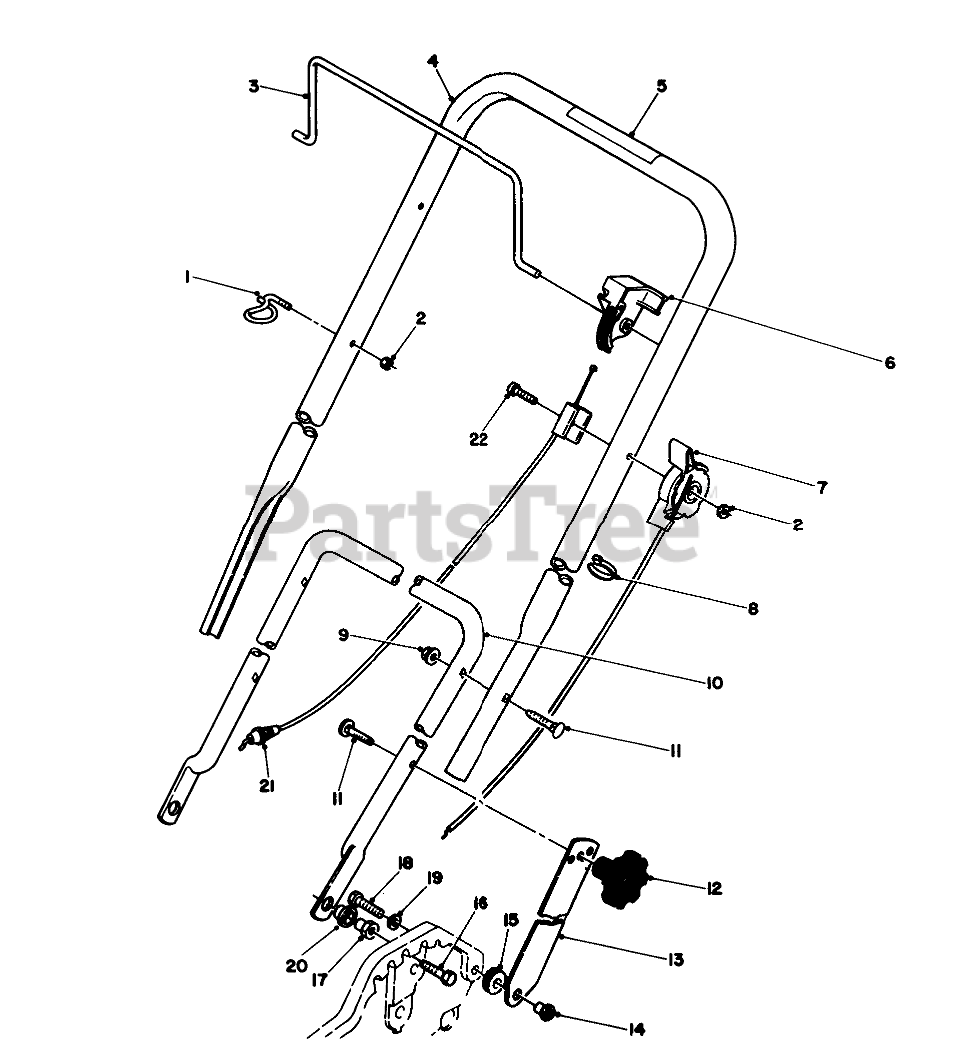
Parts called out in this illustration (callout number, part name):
1	ROPE GUIDE
2	NUT-LOCK, NI
3	Bar-Control
4	Handle-Upper (Incl. Ref. #5)
5	WARNING DECAL
6	BAIL STOP/LEVER
7	THROTTLE CABLE
8	TIE-CABLE
9	NUT-LOCK, NI
10	LOWER HANDLE(CROM)
11	SCREW
13	HANDLE LATCH
14	POST-MOUNTING, LINKAGE
15	GROMMET
16	SCREW-HH
17	HANDLE PIVOT NUT
18	SCREW-HH
19	WASHER-LOCK
20	FLANGE BUSHING
21	BRAKE CABLE
22	SCREW-HH
